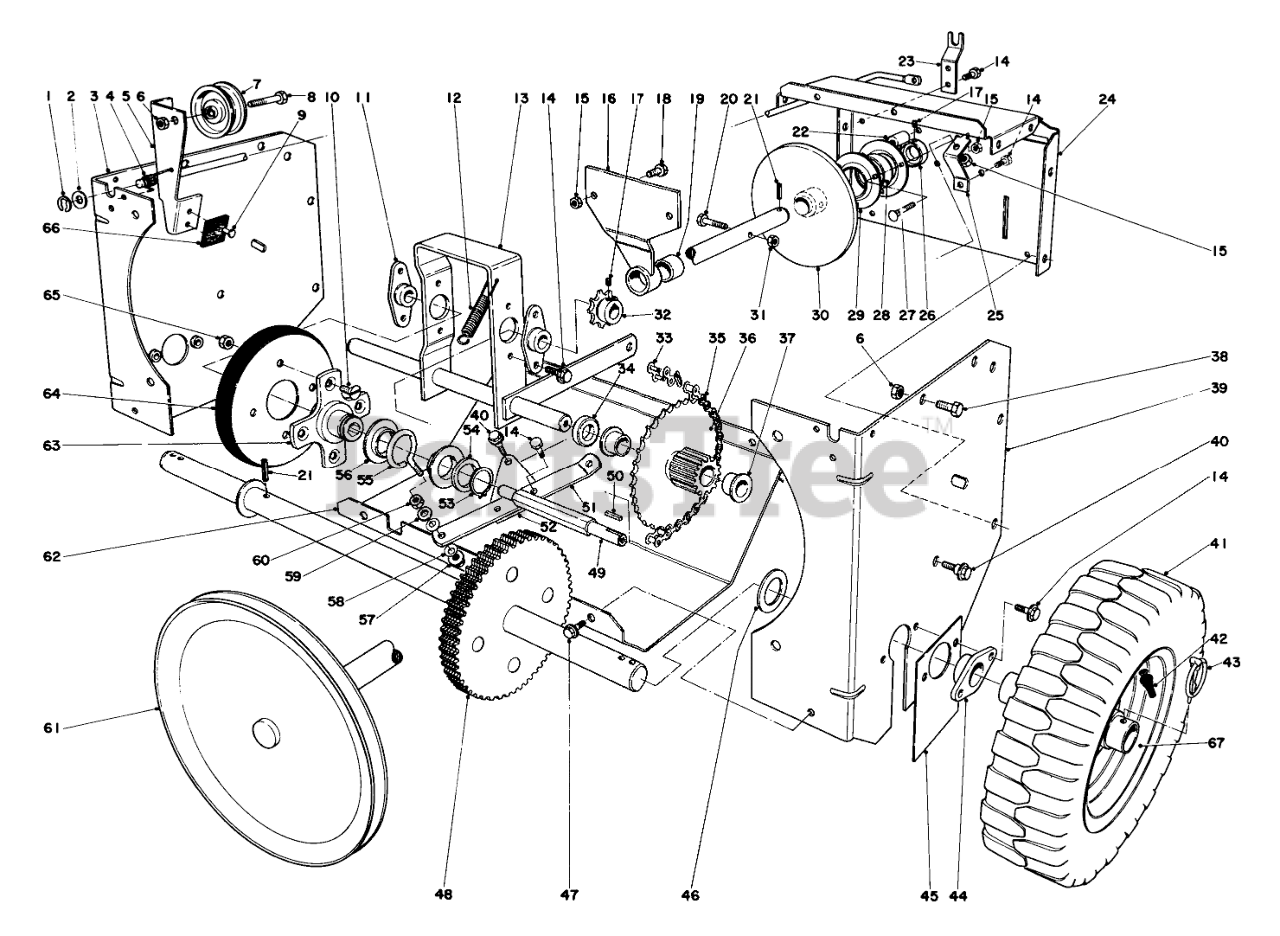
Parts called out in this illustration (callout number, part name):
1	RING-CLIP
2	WASHER-FLAT
3	RH TRACT SIDE PLT R
4	TORSION CLUTCH SPRING
5	Clutch Rod & Pad Assembly
6	NUT-HEX
7	PULLEY-IDLER
8	SCREW-HH
9	.187 X 1/4 POP RIVET
10	5/16-18X5/8 FLT HD MS
11	BEARING-WHEEL, FRICTION
12	TENSION SPRING
13	PIVOT SHAFT WA B
14	SCREW-HWHTF
15	NUT-LOCK, CONE
16	SHAFT SUPPORT WA
17	SCREW-HSH
18	SCREW-HH
19	Needle Bearing
20	SCREW-HH
21	PIN-ROLL, SLOTTED
22	DRIVE SET BRC SPACER
23	CLUTCH ROD SUPPORT
24	Center Frame
25	PIVOT BRACKET
26	EXT LOCKING COLLAR
27	SCREW-CARR
28	BALL BRG W/COLLAR
29	BRG FLANGE
30	FRICTION PLT WA
31	NUT-LOCK, CONE
32	SPROCKET
33	LINK-CONNECTING
34	COSHAFT SPACER
35	ROLLER-CHAIN
36	Sprocket and Gear (Incl. Ref 37)
37	BUSHING
38	SCREW-HH
39	LH TRACT SIDE PLT R
40	SHOULDER SCREW
41	Tire
42	STEM-VALVE
43	PIN-LYNCH
44	AXLE BEARING
45	Cover
46	WASHER
47	SCREW-HWH
48	AXLE & GEAR WA
49	FRICTION WHL SHAFT
51	SHIFT LINKAGE
52	PIVOT PLATE
53	RING-RETAINING
54	WASHER-THRUST
55	SLIDER RING COLLAR
56	SLIDER RING
57	NUT-LOCK, FLANGE
58	WASHER-SPRING
59	WASHER-FLAT
60	Nut
61	Drive Shaft
62	LOWER SHIELD R
63	TRACTION DISC HUB
64	Disc
65	Nut
66	BRAKE PAD
67	Wheel
